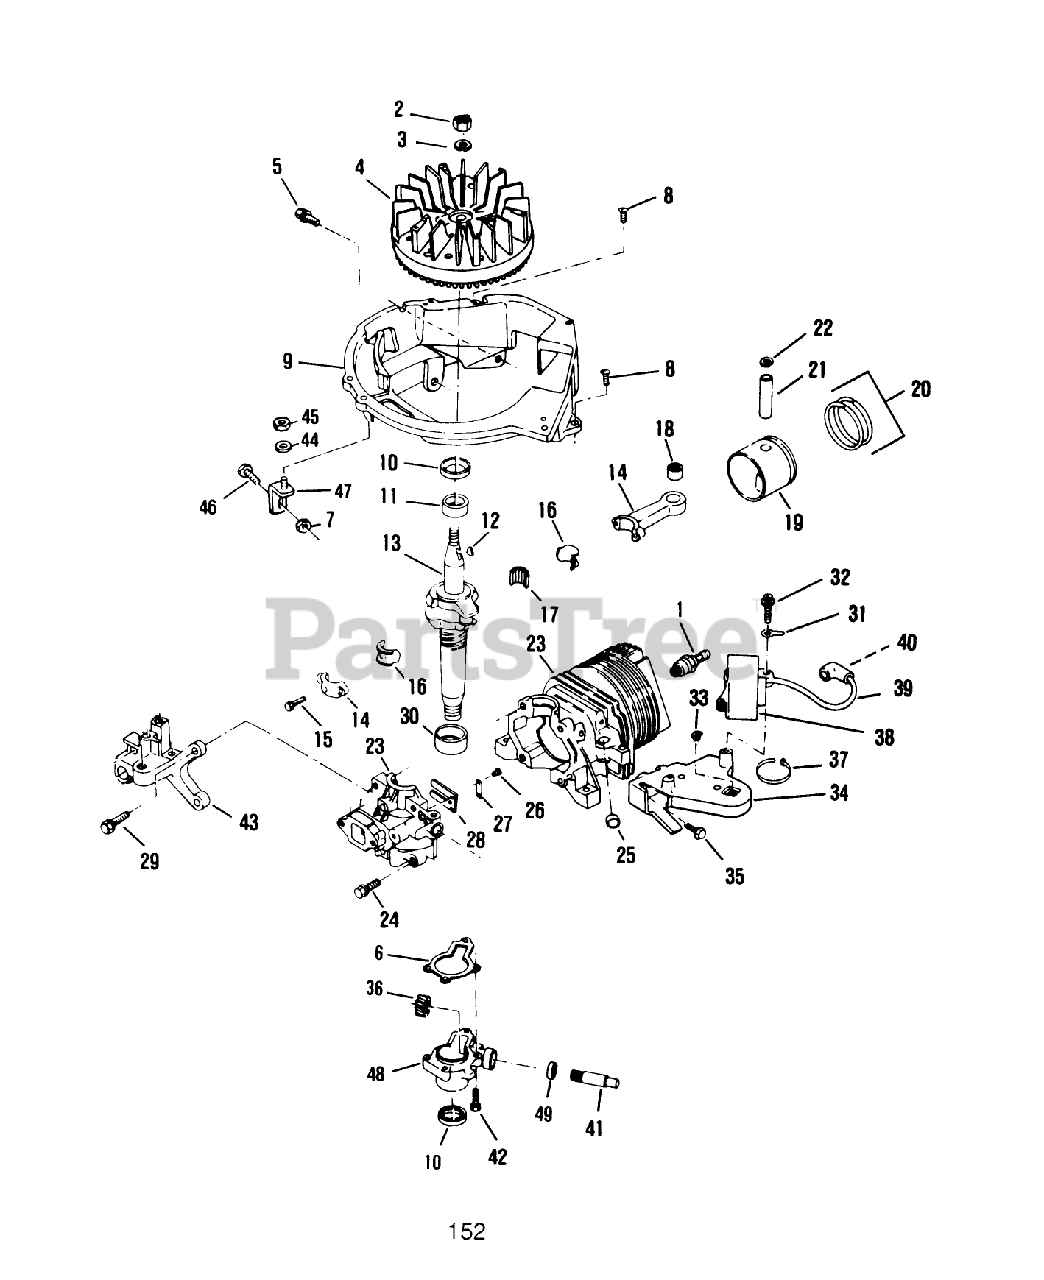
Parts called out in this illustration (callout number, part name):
2	NUT
4	FLYWHEEL ASSY F
5	SCREW-SEMS
6	GASKET S
7	NUT-LOCK F
8	SCREW F
10	SEAL-OIL
11	BEARING V
12	KEY
15	SCREW-HSH
16	LINER ASM
17	BEARING-NEEDLE
18	BEARING AY F
22	RING-RETAINING
24	SCREW S
25	PLUG-CORE VF
26	SCREW-HH
27	PLATE-BACKUP, REED
30	BEARING S
31	TERMINAL S
33	NUT-CLIP
34	BRACKET S
39	HT LEAD&COVER XEV
41	DR SHAFT,PTO S
43	BRACKET-BRAKE F
44	WASHER S
45	LOCKNUT E
46	BOLT F
47	BRACE AY F
49	SEAL S
